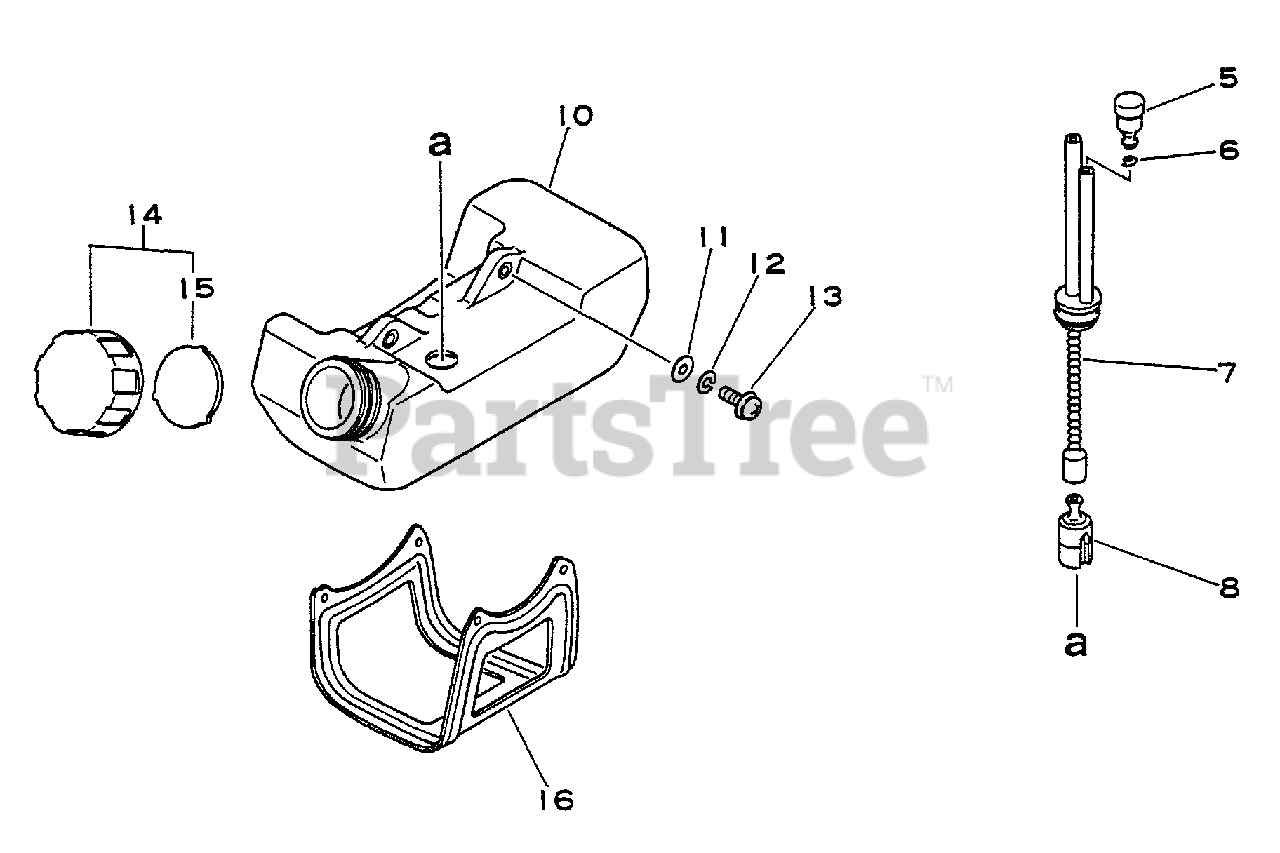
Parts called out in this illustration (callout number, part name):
5	VENT, FUEL TANK
6	CLIP - 5.5
7	FUEL PIPE ASSY
8	FILTER, FUEL
10	TANK, FUEL
11	WASHER - 5
12	LOCKWASHER - 5
13	SCREW - 5X16
14	CAP ASSY
15	GASKET, CAP
16	GUARD, FUEL TANK
